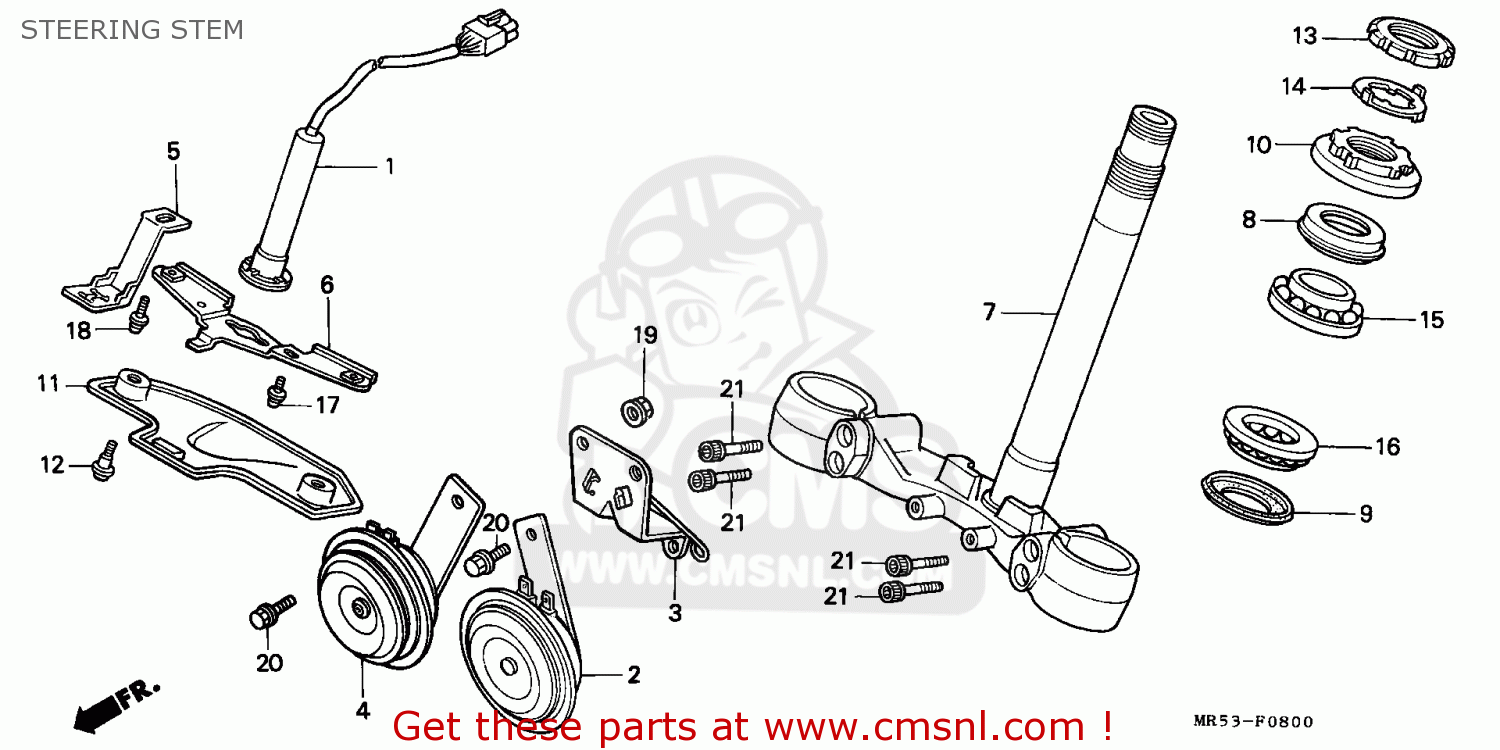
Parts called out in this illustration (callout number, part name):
1	CANCEL UNIT,WINKE
2	HORN COMP (HIGH)
3	STAY,HORN
5	SUPPORT,SENSOR
6	PLATE,WINKER CANC
7	STEM COMP,STRG
8	DUST SEAL,STRG UP
9	SEAL,HEAD DUST
10	THREAD,STRG.HEAD
11	PROTECTOR,WIND
12	SCREW SPECIAL5X12
13	THREAD B,TOP
14	WASHER
15	B/BRG RAD N/COM
16	B/BRG RAD N/COM
17	SCREW-WASH 5X8
18	SCREW-WASH.,5X12
20	BOLT,FLANGE,8X12
21	BOLT,SOCKET,8X32
